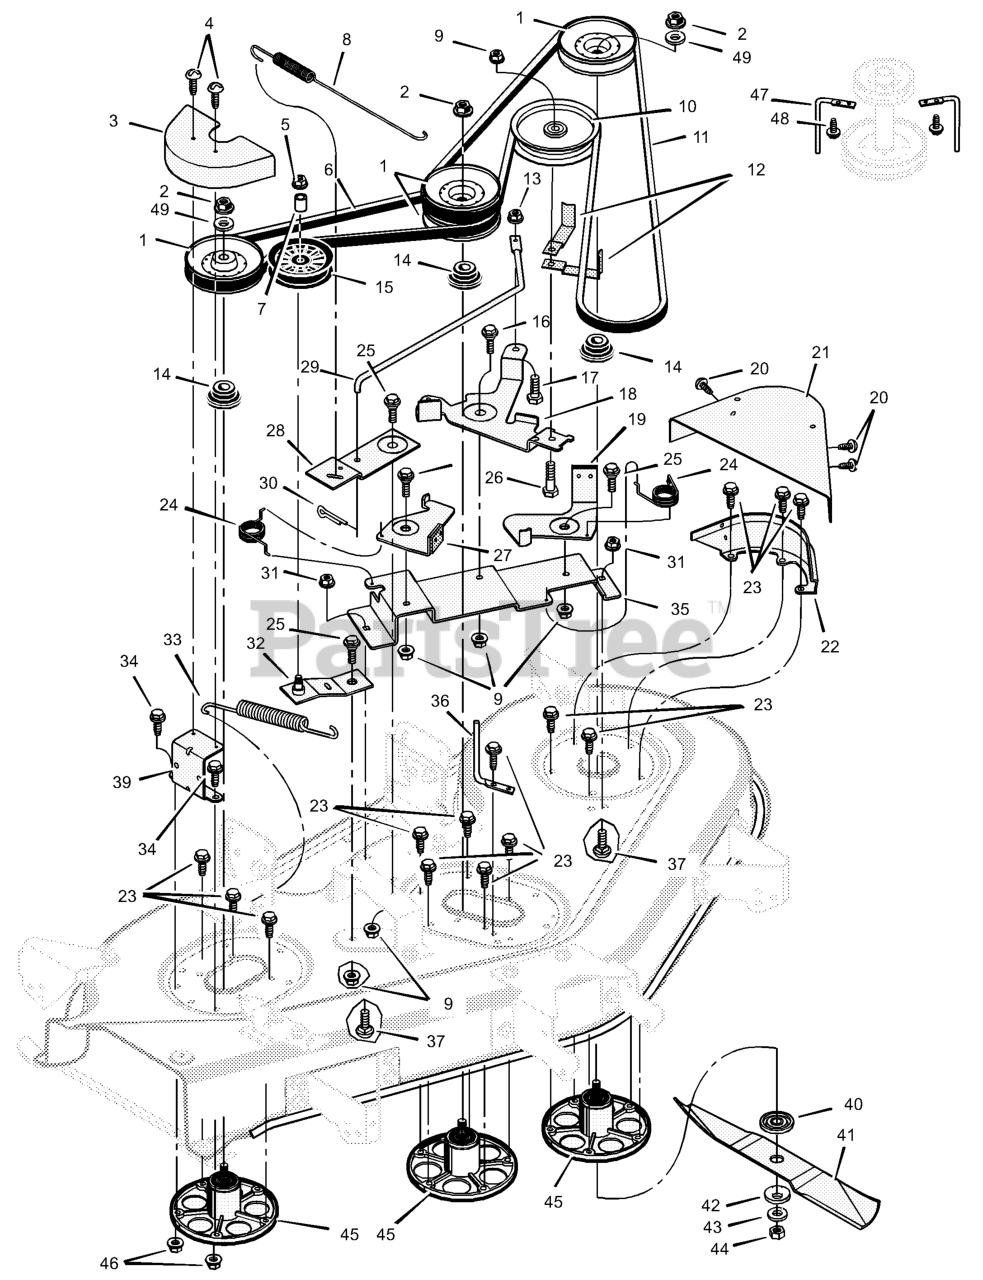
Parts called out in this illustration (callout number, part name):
3	Cover, Right Pulley
4	Screw
5	Locknut, Flange
6	Belt, Secondary
8	Spring, Extension
9	Locknut
10	Pulley, Idler
11	Belt, Primary
12	Spring, Belt Guide
13	Locknut
14	Spacer, Pulley
15	Pulley, Backside Idler
16	Bolt, Shoulder
17	Bolt, Shoulder
18	Bracket, Idler
19	Assembly, Brake Arm
21	Cover, Left Pulley
22	Bracket, Pulley Cover
23	Bolt
24	Spring, Torsion
25	Bolt, Shoulder
26	Bolt
27	Assembly, Brake Arm
28	Bellcrank
30	Pin, Cotter
31	Locknut, Flange
32	Assembly, Idler Arm
33	Spring, Extension
34	CAPSCREW, Hex Head, 5/16-18 x 1
35	Bracket, Brake Mounting
36	Rod, Belt Guide
37	Bolt, Carriage
38	Screw
39	Bracket, Cover
40	Adapter, Blade
45	Assembly, Jackshaft Housing
46	Nut
47	Guide, Belt
48	Screw
49	Washer
